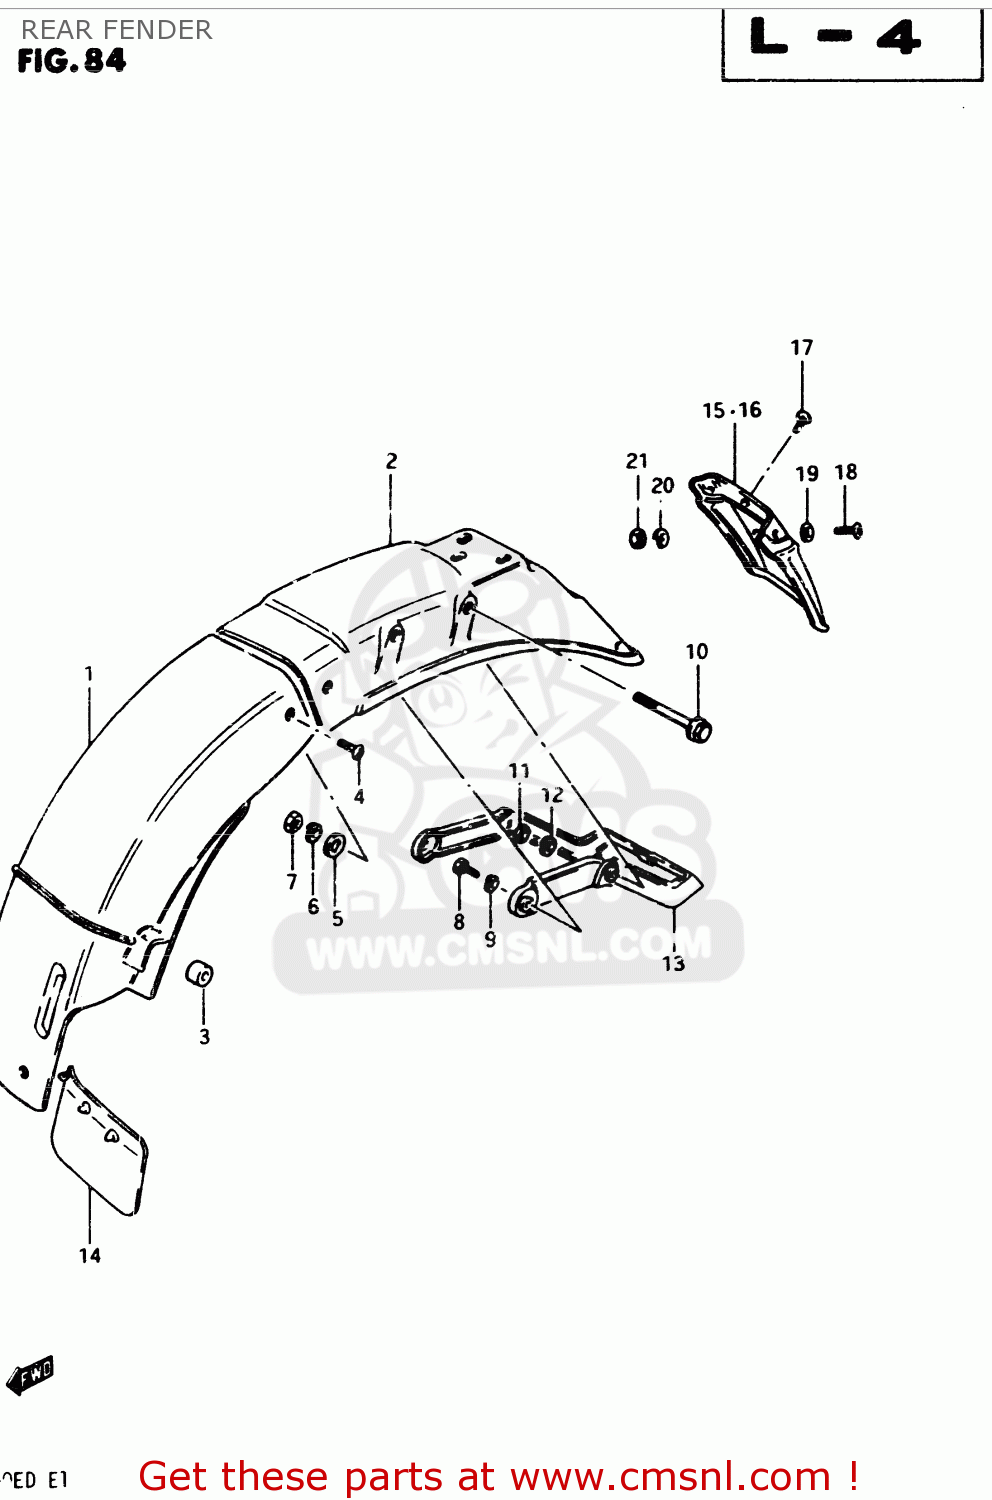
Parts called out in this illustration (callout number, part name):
1	FENDER,REAR
2	BODY,REAR FENDER,REAR
3	CUSHION
4	SCREW
5	WASHER (5.5X16X1.2)
6	LOCK WASHER
7	NUT
8	BOLT, UPPER
9	LOCK WASHER
10	BOLT
11	NUT
12	LOCK WASHER
13	REINFORCEMENT,REAR FENDER
14	GUIDE,RR FENDER MUD
15	EXTENTION, REAR FENDER
16	EXTENTION, REAR FENDER
17	SCREW 6X12
18	SCREW
19	WASHER(6.5X18X1)
20	LOCK WASHER
21	NUT
